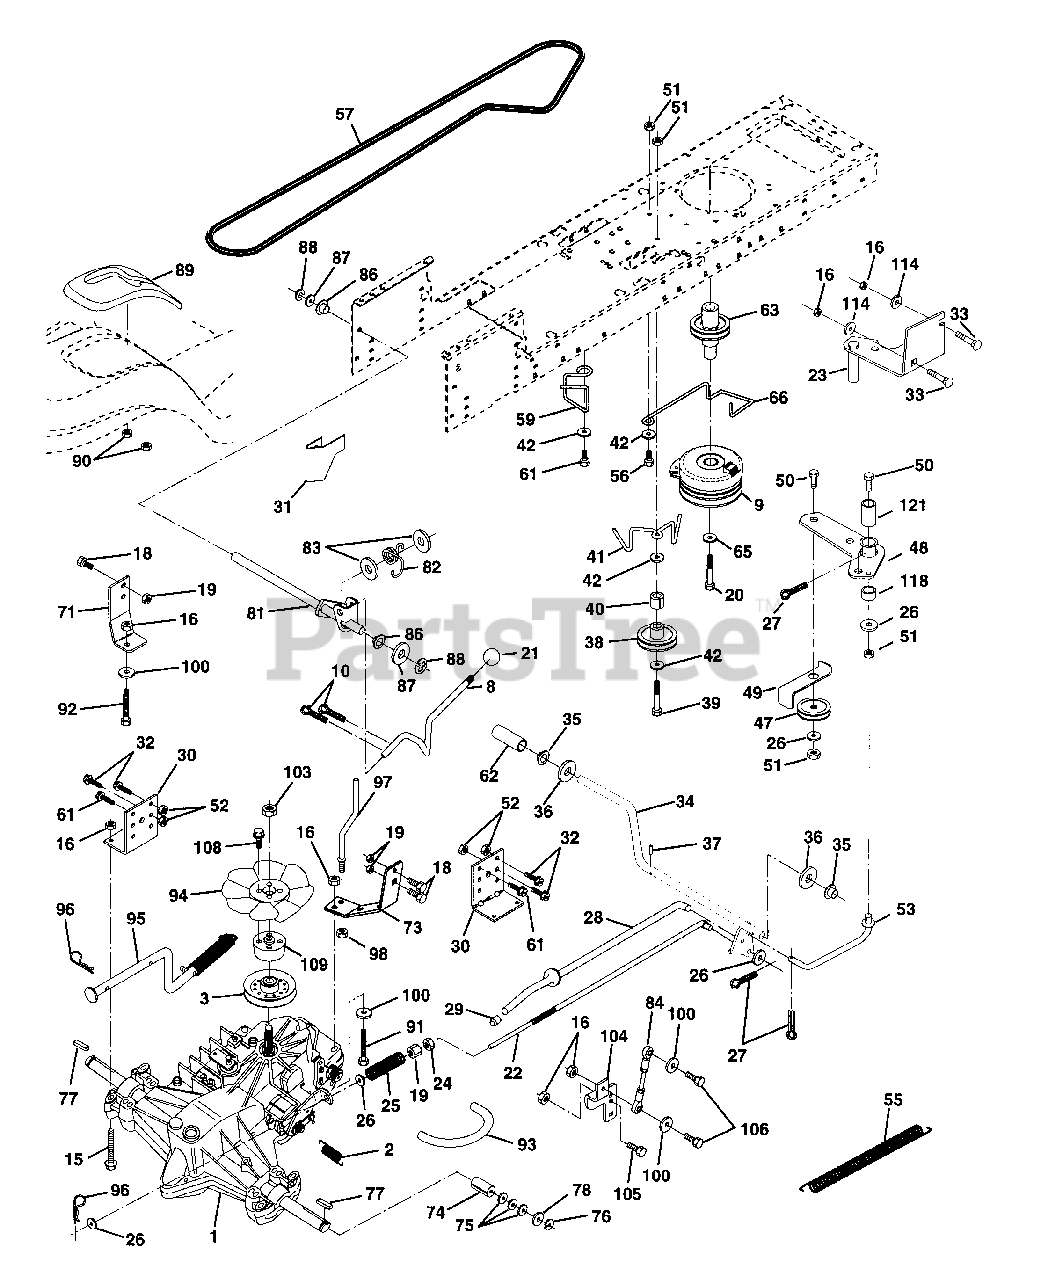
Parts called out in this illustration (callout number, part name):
1	Transaxle Hydro Gear, Model No. 310-0500
2	Spring, Return, Brake
3	Pulley, Transaxle
8	Rod Shift Fender STLT
9	Clutch, Elect. EVX LT Mag 5217-2
10	Pin Cotter 1/8 x 1 CAD
15	Bolt, Hex Flghd 5/16-18 Gr. 5
16	Nut Lock Hex W/Ins. 5/16-18 Unc P
18	Bolt Fin Hex 3/8-16 Unc x 1 Gr. 5
19	Nut Lock Hex W/Wsh 3/8-16 Unc
20	Bolt Hex 7/16-20 x 4-1/4 Ga. 1.38
21	Knob, Duckhead 1/2-13
22	Rod, Brake Hydro
23	Bracket, Asm Clutch Mtg EVX
24	Nut
25	Spring, Brake Rod
26	Washer
27	Pin Cotter 1/8 x 3/4 CAD.
28	Rod, Parking Brake
29	Cap, Parking Brake
30	Bracket, Transaxle
31	Keeper Belt Lh
32	Bolt Hex Hd 5/16-18 Unc x 3/4
33	Bolt Rdhd Sqnk 5/16-18 UNC x 3/4
34	Shaft, Foot Pedal
35	Bearing, Nylon
37	Pin, Roll
38	Pulley, Idler, Flat
40	Spacer, Split
41	Keeper, Belt Idler
42	Washer 13/32 x 13/16 x 12 Gauge
47	Pulley, Idler, V-Groove
48	Bellcrank Assembly
49	Retainer, Belt
50	Bolt
52	Nut Crownlock 5/16-18
53	Link, Clutch
55	Spring, Return, Ciutch
56	Bolt Fin Hex 3/8-16 UNC x 1-1/4
57	V-Belt, Ground Drive
59	Keeper, Center Span
60	Keeper Belt Engine
61	Screw Thdrol. 3/8-16 x 3/4 Ty. TT
62	Cover, Pedal
63	Pulley, Clutch Electric EVX
65	Washer
66	Keeper Belt Engine Full-Proof
71	Strap Torque Lh Hydro
73	Strap Torque Rh Hydro
74	Spacer, Split
75	Washer 25/32 x 1-1/4 x 16 Gauge
77	Key, Square
78	Washer 25/32 x 1-5/8 x 16 Gauge
81	Shaft Asm. Cross Hydro
82	Spring Torsion T/A
83	Washer 17/32 x 3/4 x 16 Ga.
84	Rod, Tie Hydro
86	Bushing Rod Steering 629/632 ID
87	Washer 21/32 x 1-1/4 x 16 Ga.
88	Ring Klip #5304-62
89	Console, Shift
90	Nut, Self-Thd Wsh-hd 1/4 Zinc
91	Bolt Fin Hex 5/16-18 x 2-1/4
92	Bolt Fin Hex 5/6-18 Unc x 1-1/2
93	Line Fuel Hydro 4"
94	Fan, Hydro 7"
95	Control Asm Bypass Hydro
96	Retainer Spring 1" Zinc/Cad
97	Keeper Belt Rh Hydro
98	Nut Keps Hex 3/8-16 Unc
100	Washer 11/32 x 3/4 x 16 Ga.
103	Nut Nylon Insert 1/2-20 Unf.
104	Arm, Control Hydro
105	Screw Cap Hex 5/16 x 18 x 1
106	Bolt Fin Hex 5/16-18 Unc x 1-1/4
108	Screw Hex Wh Hd #10-24 x
109	Adaptor Fan Hydro LT Hyd Alum
114	Washer 11/32 x 3/4 x 14 Ga.
118	Spacer, Bellcrank
121	Nyliner Clutching STL
